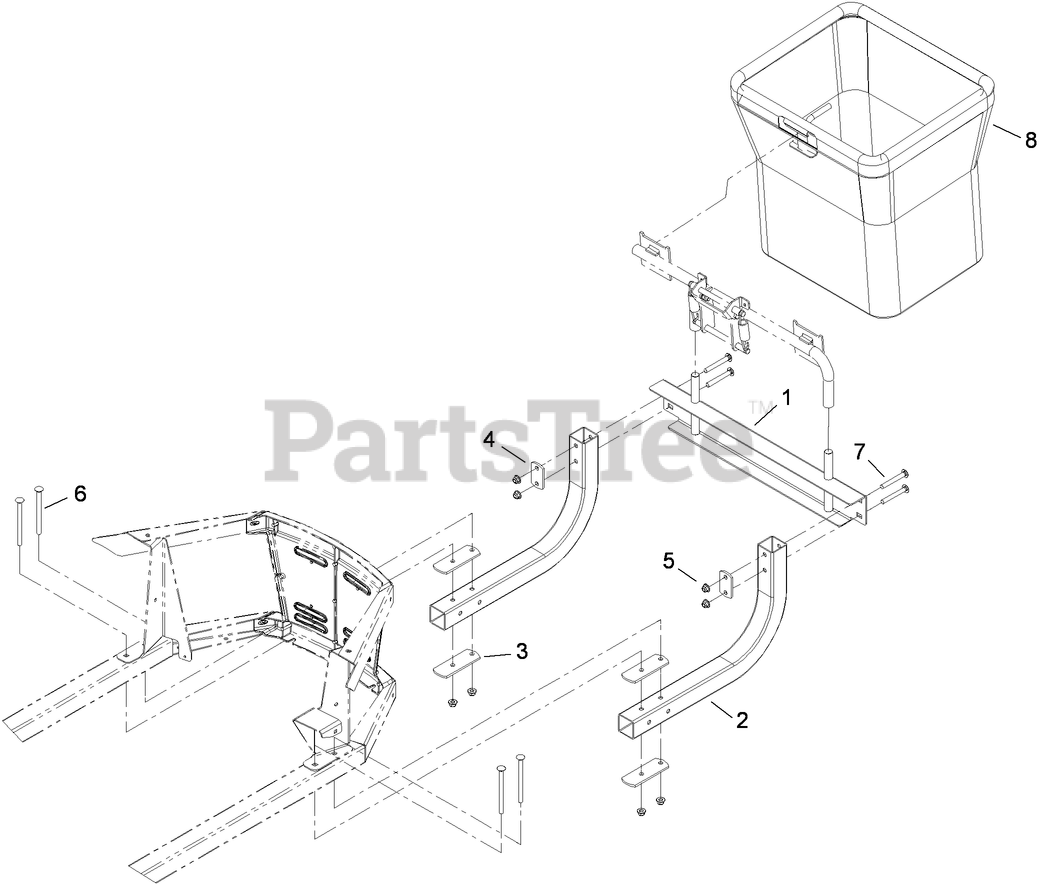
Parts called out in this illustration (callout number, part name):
1	BAGGER HITCH ASM
2	TUBE-HITCH, BAGGER
3	PLATE-STIFFENER
4	PLATE-STIFFENER
5	NUT-HF, NI
6	BOLT-CARR
7	SCREW-CARR
8	BAG ASM
